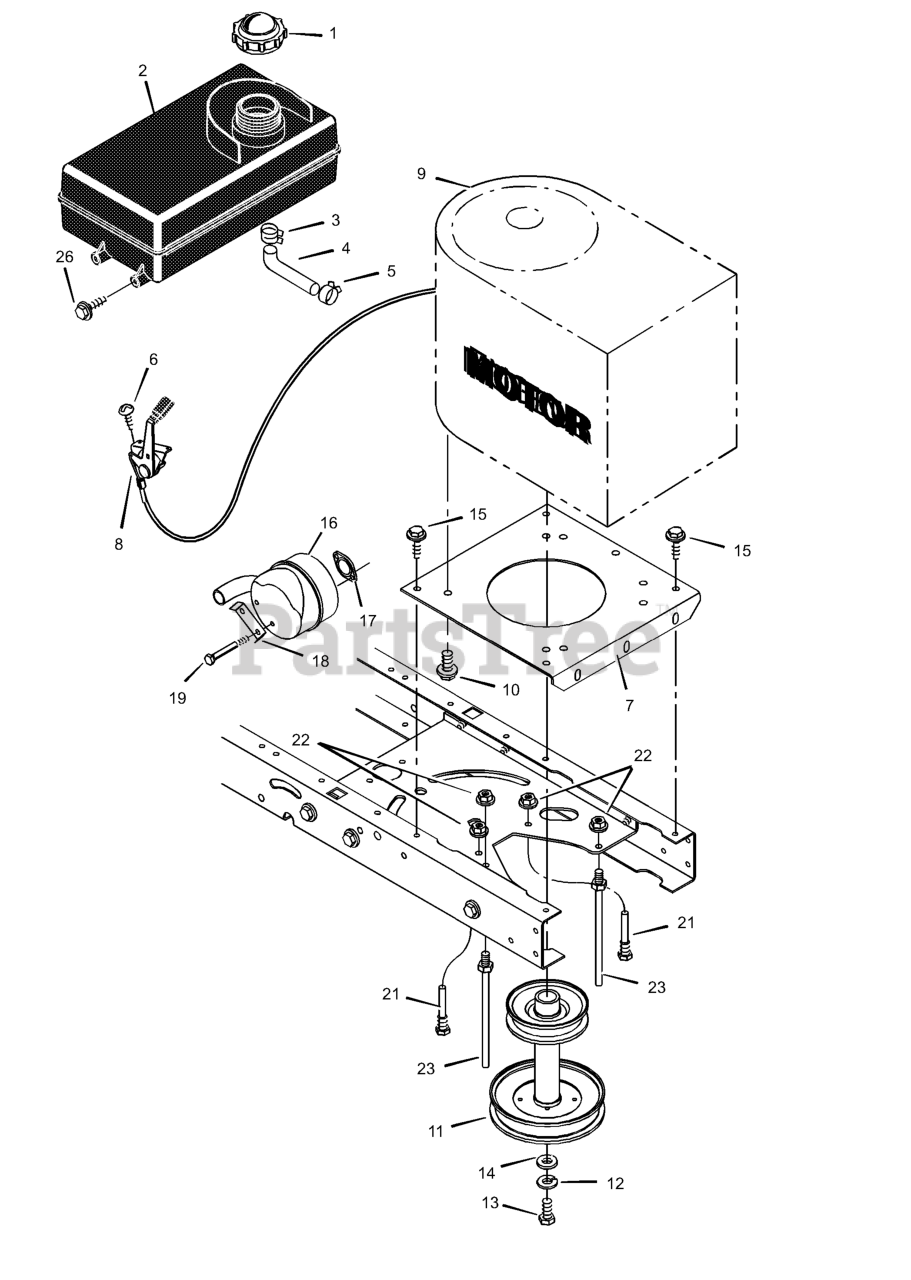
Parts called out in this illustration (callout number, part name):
1	Fuel Cap
2	TANK, Fuel 1.4 Gal.
3	Hose Clamp
4	Fuel Line (Must cut to length)
5	Hose Clamp
7	Plate, Engine
8	Throttle Control
9	Engine *
10	Bolt, Engine Mount
11	STACK PULLEY ASSEMBLY
12	Lockwasher
13	Bolt, Hex
16	Muffler
17	GASKET, Exhaust
18	Lock, Screw
21	Guide, Belt
22	Nut, Flange
23	Guide, Belt
